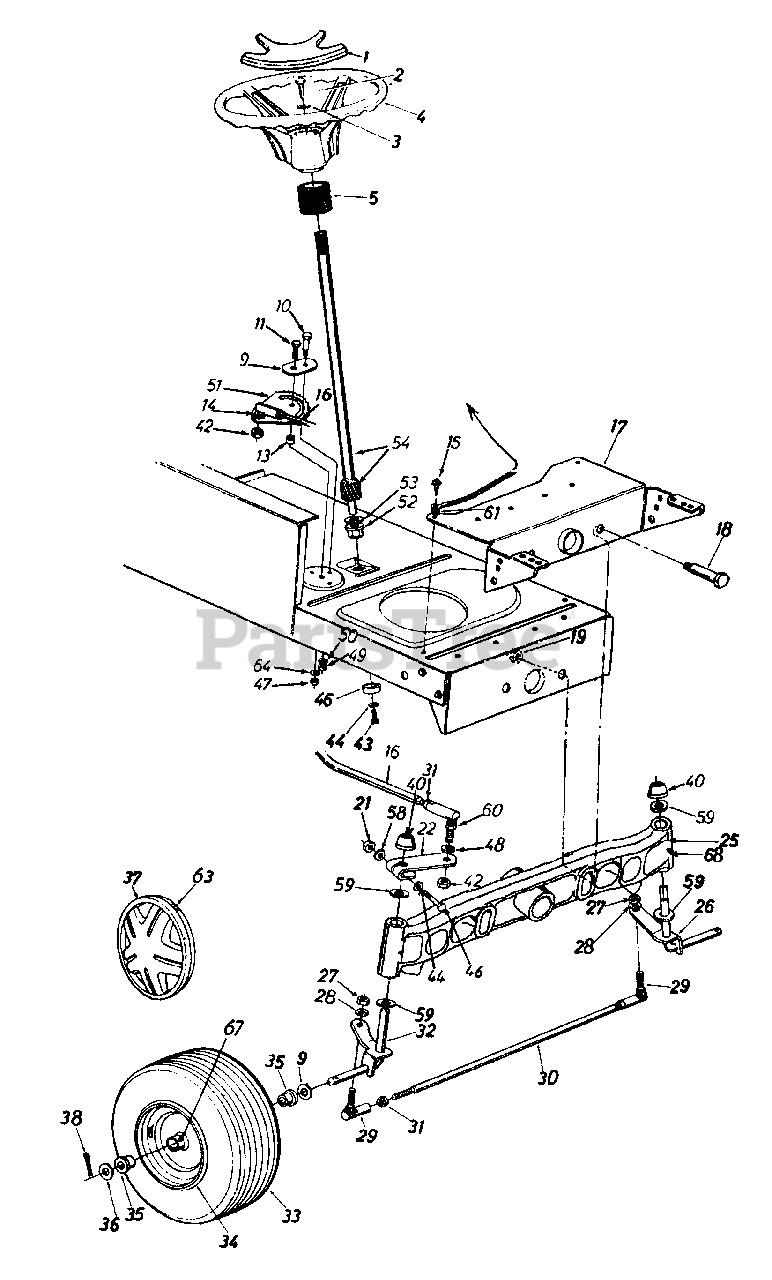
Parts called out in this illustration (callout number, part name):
1	Steering Wheel Cap
2	Hex Bolt 5/16-18 x 1" Lg.
3	Belleville Wash. .345" I.D.
4	Steering Wheel
5	Steering Bellow - 9"
9	Retainer Plate
10	Shoulder Bolt .437" Dia. x .35" Lg. - 5/16-18 Thd.
11	Hex Bolt 3/8-24 x 1.0" Lg. (Grade 5)
13	Spacer .380" I.D. x .625" O.D. x .227
14	L-Wash. 3/8" I.D. (H.D.)
15	Hex Wash. Hd. Self-Tap Scr.
16	Steering Drag Link
18	Shoulder Bolt .498" Dia. x 2.04" Lg. - 3/8-16 Thd.
19	Flanged Hex Nut 3/8-16 Thd.
21	Hex L-Nut 5/16-24 Thd.
22	Steering Arm Front Axle
25	Pivot Bar Ass'y.
26	Front Axle Ass'y. - L.H.
27	Hex Nut 3/8-24 Thd.
28	L-Wash. 3/8" I.D.
29	Ball Joint 3/8-24 Thd.
31	Hex Jam Nut 3/8-24 Thd.
32	Front Axle Ass'y. - R.H.
36	Fl-Wash. .635" I.D. x 1.59" O.D.
37	Hub Cap
38	Cotter Pin 1/8" Dia. x 1.25"
40	Push Cap 5/8" Dia. Rod
42	Hex Jam Nut 3/8-24 Thd.
43	Torx Bolt 5/16-18 x .63" Lg.
44	L-Wash. 5/16" I.D.
47	Hex Cent. L-Nut 3/8-24 Thd.
49	Hex Cent. L-Nut 5/16-18 Thd.
50	L-Wash. 5/16" I.D.
51	Steering Gear Segment
52	Hex . Flg. Brg. 5/8" I.D.
53	Fl-Wash. (Hardened)
54	Steering Shaft
58	Wave-Wash. .32" I.D. x .62" O.D.
59	Fl-Wash. (Hardened)
60	Drag Link Ball Joint 3/8-24 Thd.
61	Ext. L-Wash. 5/16" I.D.
63	Spring Clip
64	Bell-Wash. .39" I.D. x 1.38" O.D.
67	Grease Fitting
68	Grease Fitting
